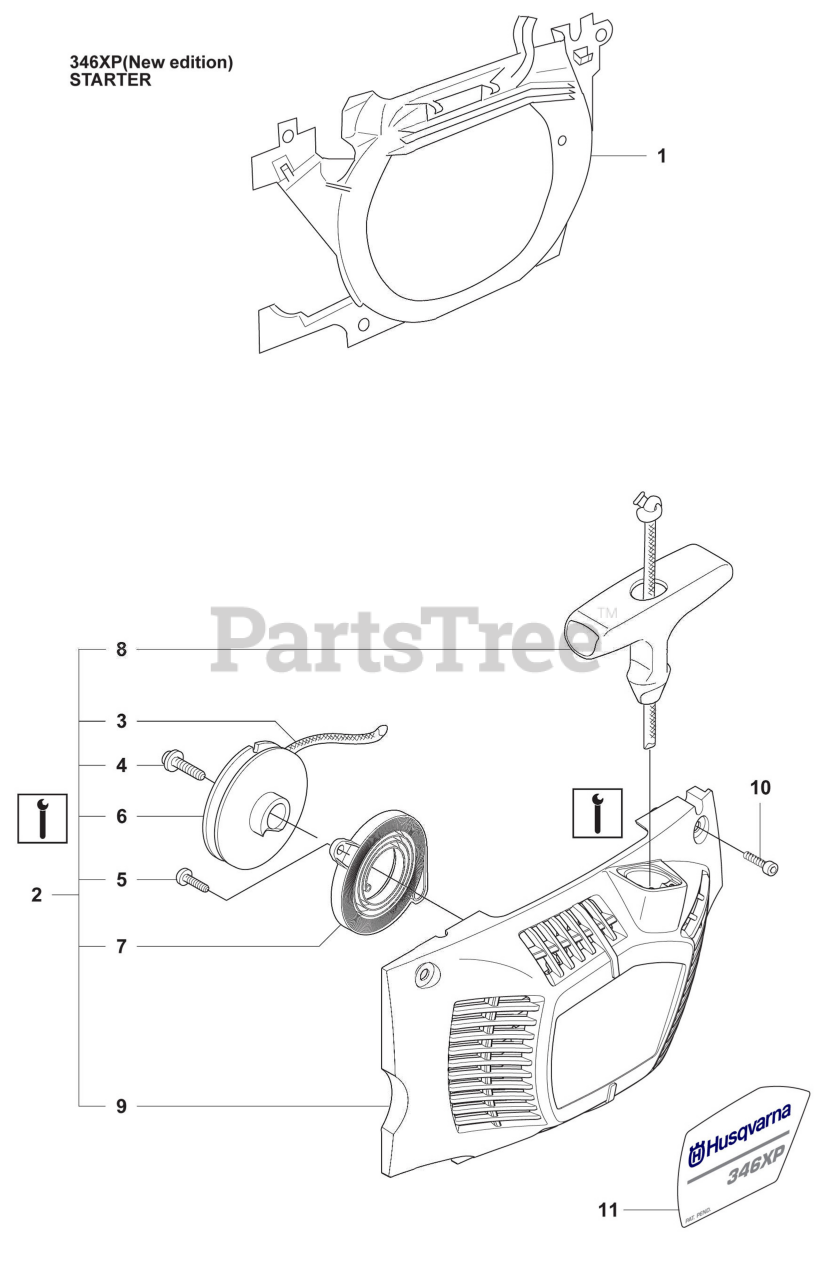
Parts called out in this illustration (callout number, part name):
1	Air Conductor
2	Recoil Starter
3	Starter Rope
6	Starter Pulley
7	Return Spring
9	Starter Housing
10	Screw, Citxpanmo
11	Label
